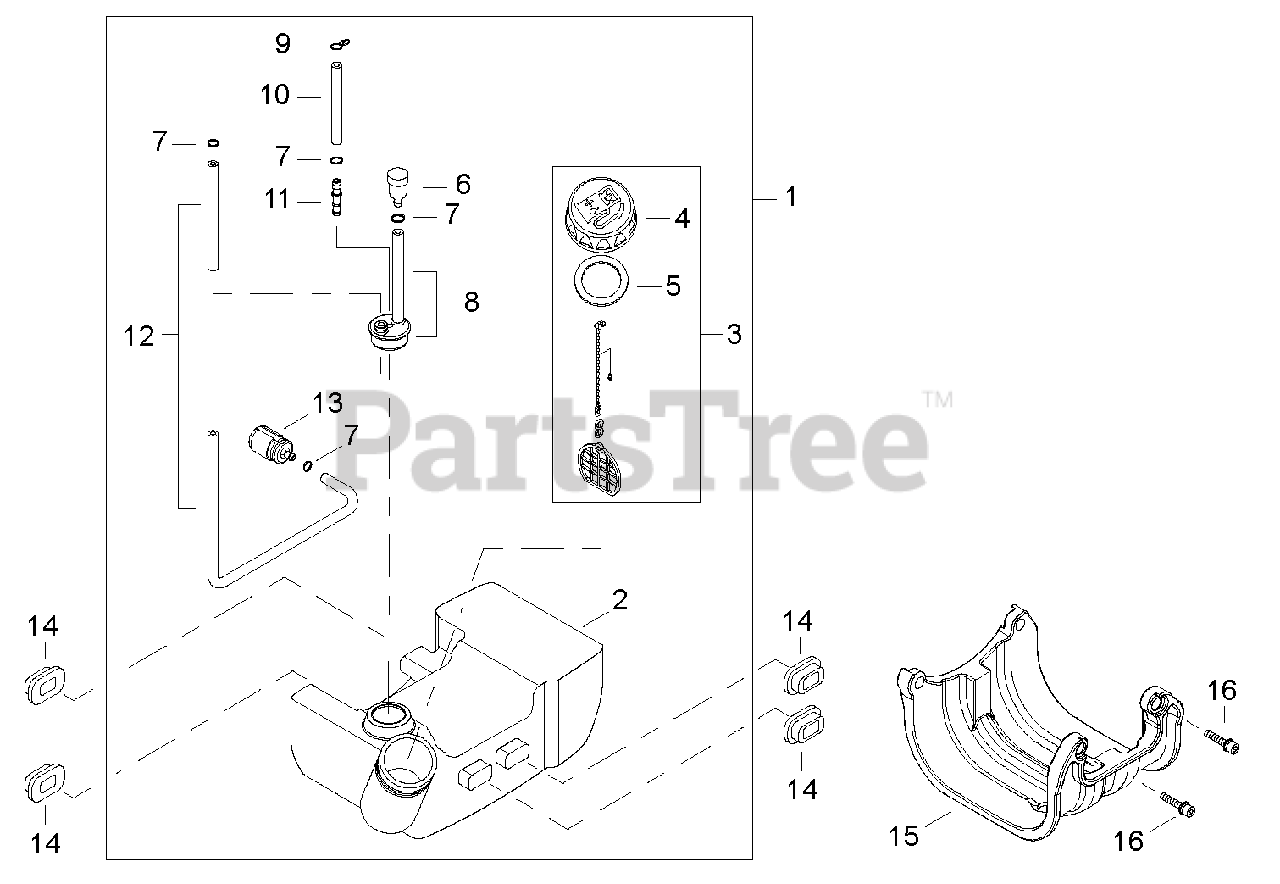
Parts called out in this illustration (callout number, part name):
1	FUEL TANK ASSY
2	TANK, FUEL
3	CAP ASSY
4	CAP, FUEL
5	GASKET, CAP
6	ELEMENT, BREATHER
7	RING, RETAINING - 6
8	GROMMET
9	CLIP - SPRING
10	PIPE
11	CONNECTOR, PIPE
12	PIPE - FUEL
13	FILTER, FUEL
14	CUSHION, FUEL TANK
15	GUARD, FUEL TANK
16	SCREW - 5X20
